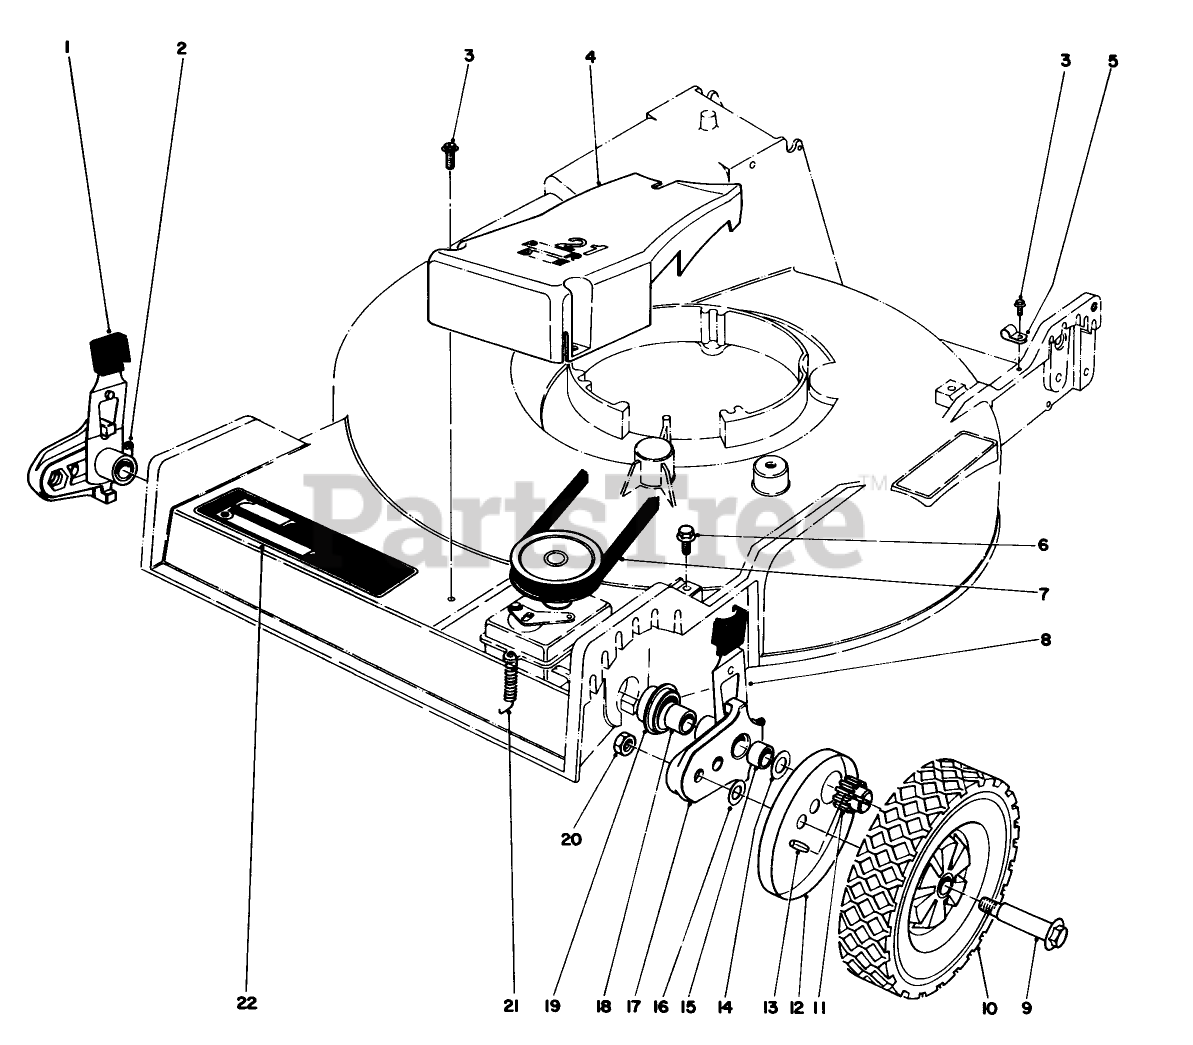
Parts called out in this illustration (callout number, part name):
1	KNOB-ARM
2	FITTING-GREASE
3	SCREW
5	CLAMP-NYLON
6	SCREW-THD ROLL, HWH
7	BELT-V
9	BOLT-WHEEL
14	WASHER-THRUST
15	Bushing
16	WASHER
17	PIVOT ARM ASM
19	END CAP
21	TENSION SPRING
